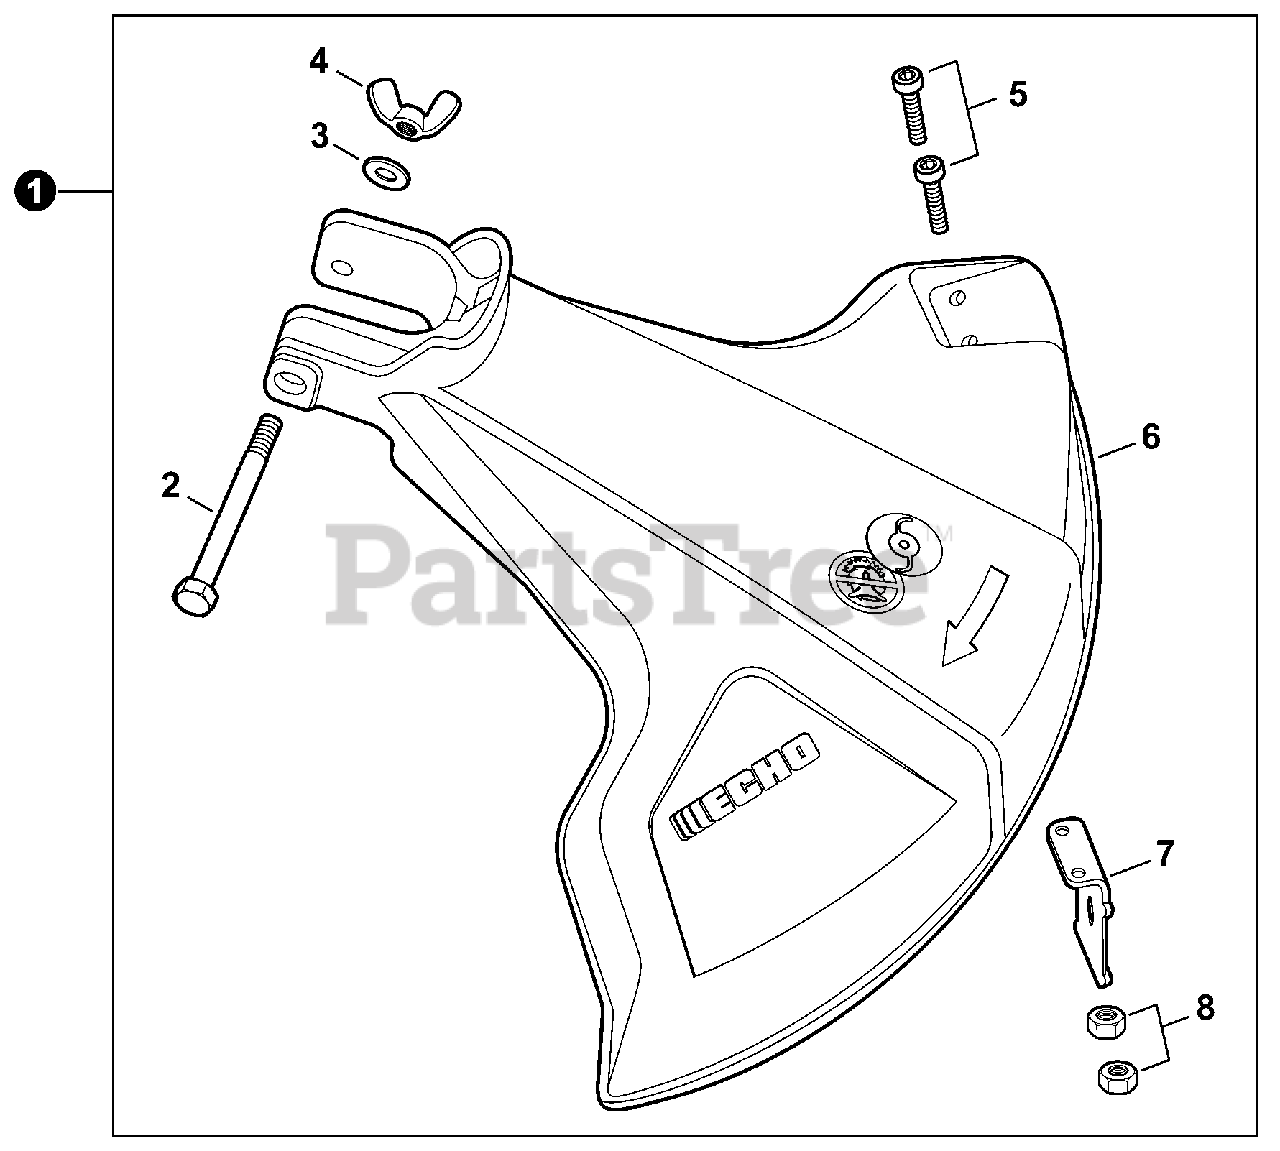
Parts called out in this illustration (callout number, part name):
1	DEBRIS SHIELD ASSY
2	BOLT 1/4-20×2"
3	WASHER, 1/4"
4	NUT, WING 1/4-20
5	BOLT, TORX 5×12
6	SHIELD, DEBRIS
7	CUTTER, LINE
